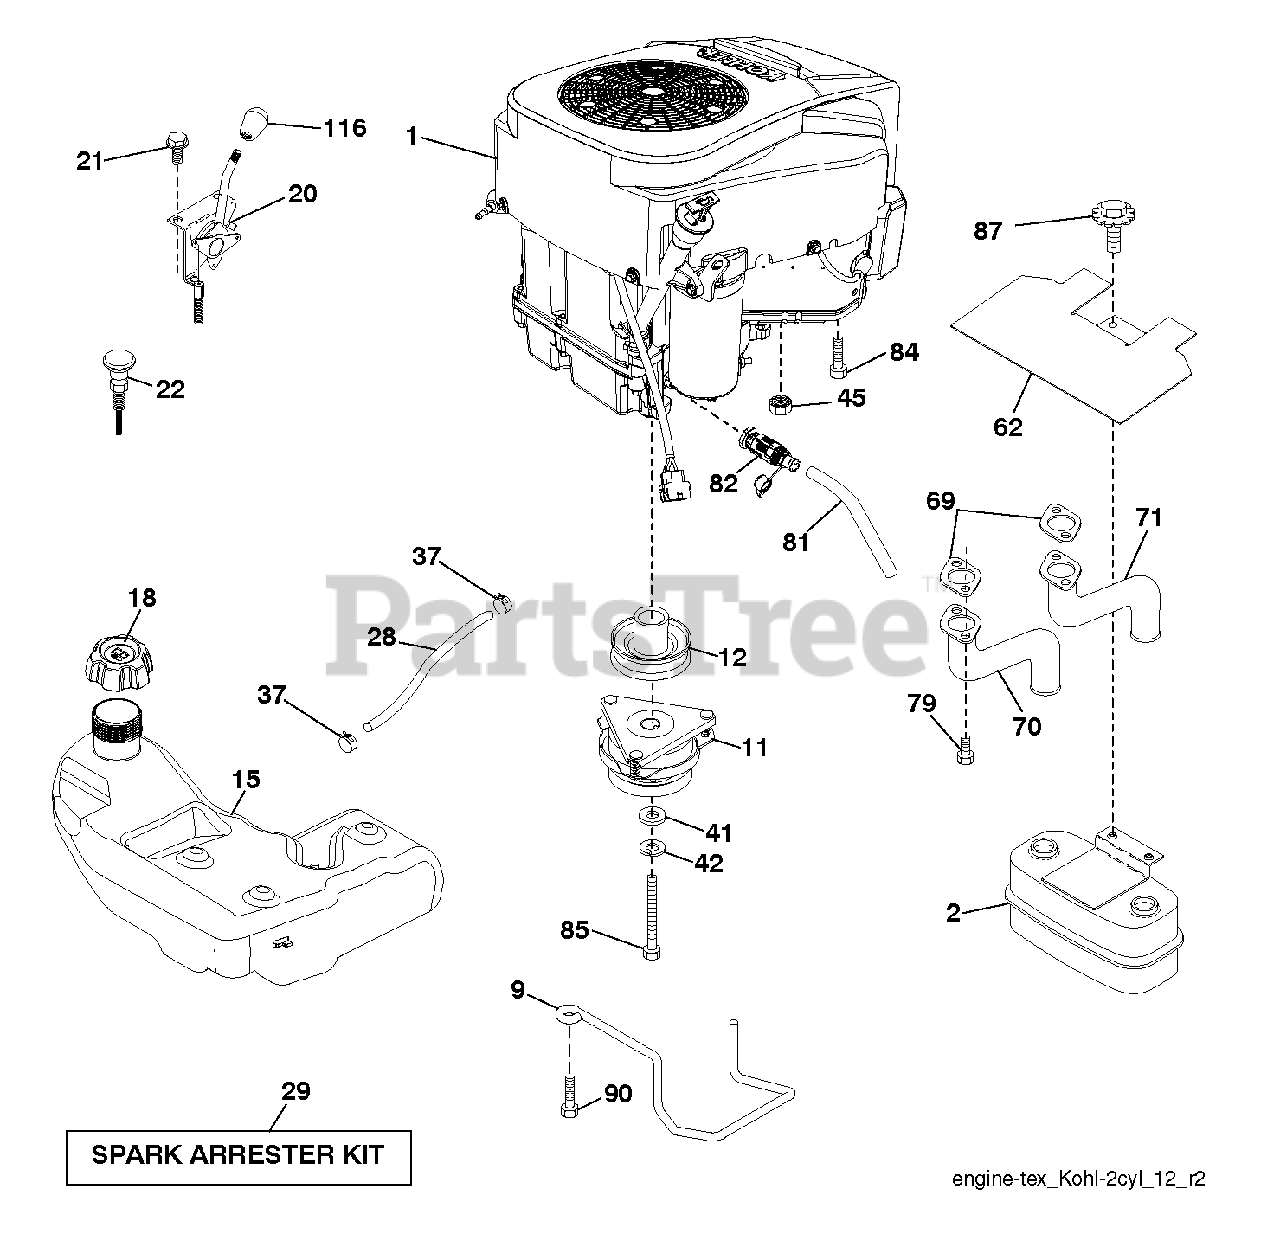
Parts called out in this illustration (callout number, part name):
2	MUFFLER.TWIN.CYL.LOW.TONE
9	KEEPER.BELT.ENGINE.4.2
12	PULLEY.ENGINE.TUFFTORQ
15	TANK.ASSY.3.GAL.EPA
18	CAP ASM.FL.RTCHT.3"GRY.E10
20	CONTROL.THROTTLE.PRO.KOHLER
21	SCREW.#10 X 0.750.BOS THREAD
22	CONTROL CHOKE
28	LINE.FUEL.64"REAR.EMIS
29	ARRESTER SPARK (OPTIONAL)
37	HOSE CLAMP
42	LOCKWASHER
62	SHIELD.HEAT.MUFFLER
70	PIPE-EXHAUST LH
71	PIPE-EXHAUST RH
79	SCREW.SOCKET HD.5/16-1
81	TUBE, DRAIN OIL ASM.
82	VALUE.OIL.DRAIN
84	SCREW 3/8-16X1
87	BOLT.5/16-18UNCX1.W/SEMS.BLK
90	SCREW 3/8-16X1
116	KNOB - SHIFT
